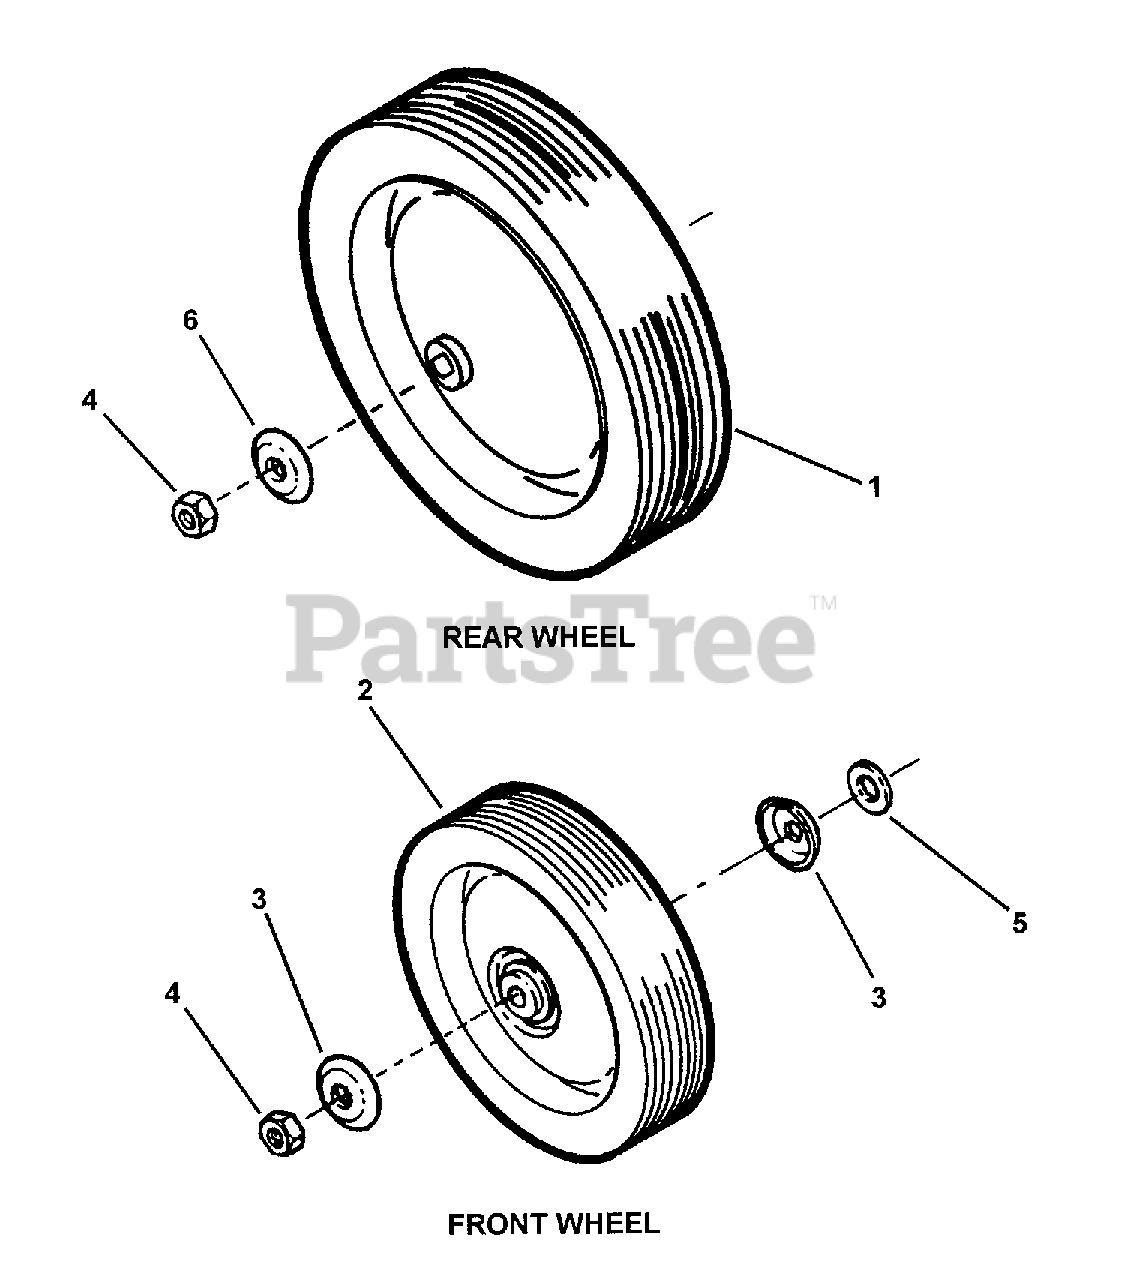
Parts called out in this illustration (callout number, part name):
1	WHEEL, Rear 10.0 x 1.75 Diamond Grey
2	WHEEL, Front 8.0 x 1.75 Diamond Black
3	HUB-CAP (Front Wheels)
4	NUT, 7/16-20 Hex Center Lock Jam
5	WASHER, 7/16" Flat
6	HUB-CAP (Rear Wheels)
